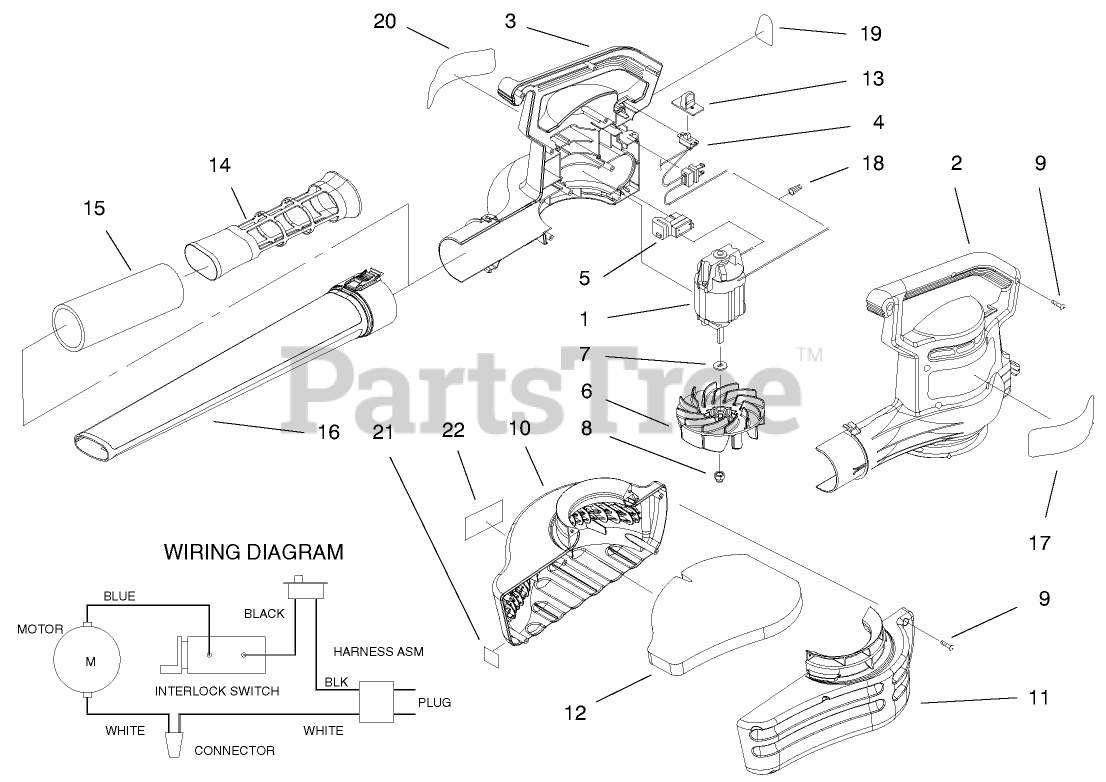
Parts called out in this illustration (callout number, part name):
1	MOTOR - ELECTRIC, 120 V
3	HOUSING, RH (BLACK)
7	WASHER-FLAT
9	SCREW-PPH
12	FOAM - INLET
14	INSERT - QUIET
18	CONNECTOR-NUT, WIRE
19	DECAL - INFORMATION
